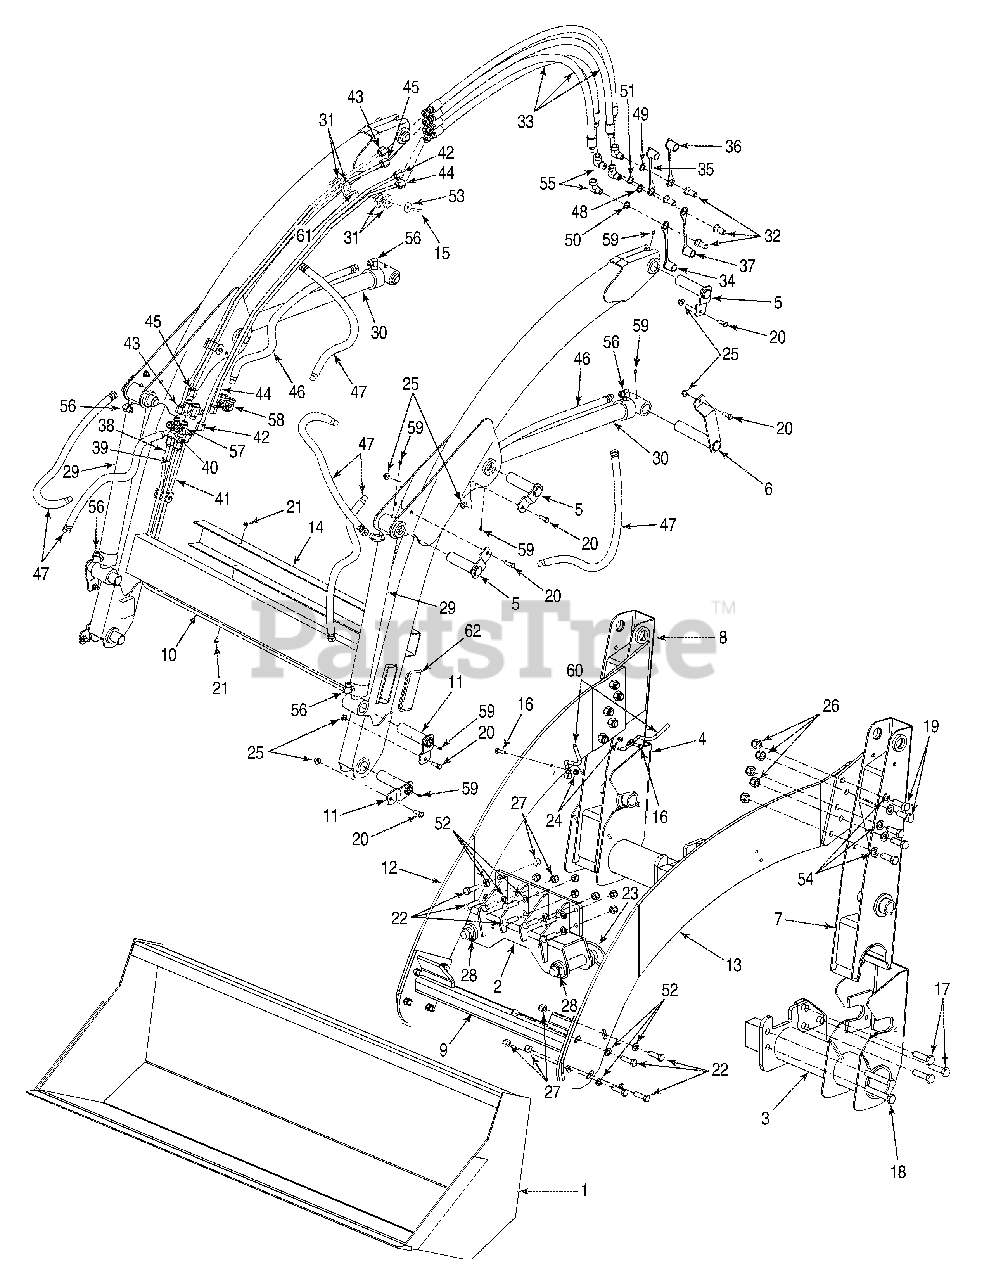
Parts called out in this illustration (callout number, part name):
1	Bucket, Loader
2	Receiver, Front Mount
7	Mast, Vertical Support LH
8	Mast, Vertical Support RH
9	Bracket, Loader Hitch
10	Boom Assembly
12	Arm, Loader Hitch LH
13	Arm, Loader Hitch RH
14	Bracket, Tube Cover
15	Screw, Hex Cap, 1/4-20 x 1.25 Gr5
16	Screw, Hex Cap, 5/16-18 x 1.0 Gr5
17	Screw, Hex Cap, M16-20 x 60
18	Screw, Hex Cap, M16-20 x 100
19	Screw, Hex Cap, 5/8-11 x 1.75 Gr8
20	Screw, Hex Cap, 3/8-16 x 1.25 Gr5
21	Screw, Hex Wash. Hd. Tapp 1/4-20 x .625
22	Screw, Hex Cap, 3/8-16 x 1.25 Gr2
23	Pin, Mounting
24	Nut, Hex Flange Lock, 5/16-18 GrF
25	Nut, Hex Flange Insert Lock 3/8-16 GrF
26	Nut, Hex Lock, 5/8-11
27	Nut, Hex Insert Lock, 1/2-13 GrB
28	Pin, Lynch
29	Cylinder, Loader Bucket
30	Cylinder, Boom Lift
31	Clamp, Tube
32	Coupling, Mail Quick Connect
33	Hose, Hydraulic, 60 inch
33	Sleeve, Hose
34	Cap, Coupler Protective - Green
35	Cap, Coupler Protective - Blue
36	Cap, Coupler Protective - Yellow
37	Cap, Coupler Protective - Red
37	Cap, Coupler Protective - Black.
38	Tube, Hyd., U Shape - Bckt Dump
39	Tube, Hyd., U Shape - Bucket Curl
40	Tube, Hyd., U Shape - BoomRaise
41	Tube, Hyd., U Shape - Boom Lower
42	Tube, Hydraulic - Bucket Curl RH
43	Tube, Hydraulic - Bucket Dump RH
44	Tube, Hydraulic - Boom Raise RH
45	Tube, Hydraulic - Boom Lower RH
46	Hose, Hydraulic, 36 inch
46	Tie, Cable - Tie hose to cylinders
47	Hose, Hydraulic, 25.5 inch
47	Tie, Cable - Tie hose to cylinders
48	Washer, Color Coded - Red
49	Washer, Color Coded - Yellow
50	Washer, Color Coded - Green
51	Washer, Color Coded - Blue
52	Washer, Flat, .535 x .93 x .09
53	Washer, Flat, .285 x 1.25 x .06
54	Washer, Flat, .64 x 1.12 x .125
55	Fitting, Elbow, 3/8-NPTF
56	Fitting, 90° Elbow, 3/8 x 3/8 Orb
57	Fitting, Branch Tee, 3/8
58	Fitting, Swivel Elbow, 3/8
59	Fitting, Lube
61	Bolt, Stacking, 1/4-20 x 3/4
62	Plug, Retangular Tube
